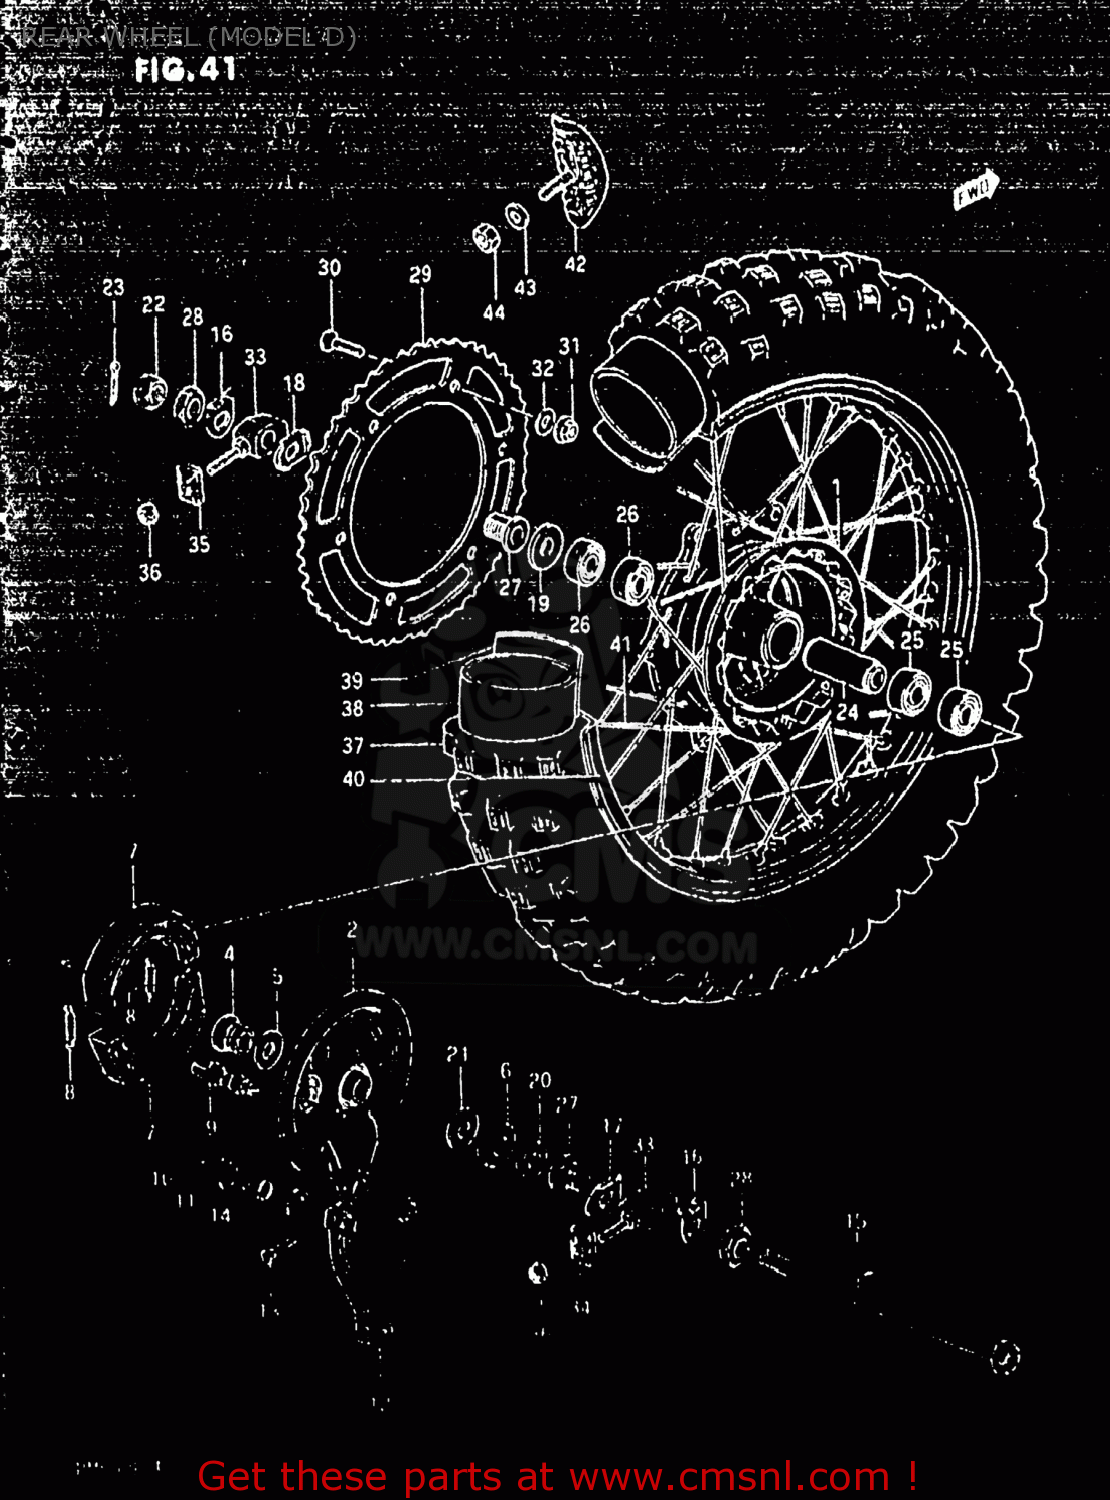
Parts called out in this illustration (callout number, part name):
1	DRUM,REAR HUB
2	PANEL SET,REAR HUB
3	SPHERICAL BRNG,TORQUE LINK
4	SPACER,RR BRAKE ANCHOR PANEL
5	SEAL,OIL(20X27X5)
6	CVR,RR BRAKE AHR PNL DUST SEAL
7	SHOE,BRAKE
8	SPRING
9	CAM,FR BRAKE
10	SPRING
11	O RING(D:2.5,ID:11.4)
12	LEVER,RR BRAKE CAM
13	BOLT
14	WASHER(12.5X20X1)
15	AXLE,REAR
16	WASHER,CHAIN ADJUSTER GUIDE
17	PLATE,CHAIN ADJUSTER,RIGHT
18	PLATE,CHAIN ADJUSTER,LEFT
19	SPACER,REAR AXLE,LEFT
20	SPACER,REAR AXLE,RIGHT
21	WASHER,THRUST
22	NUT
23	COTTER PIN
24	SPACER,REAR HUB BEARING
25	BEARING
26	BEARING
27	SPACER,CHAIN ADJUSTER
28	NUT
29	SPROCKET,REAR
30	SCREW(8X40)
31	NUT
32	WASHER
33	ADJUSTER,CHAIN
34	PLATE,CHAIN ADJUSTER GEAR
35	PLATE,CHAIN ADJUSTER GEAR
36	NUT
37	TIRE
38	TUBE,INNER
39	PROTECTOR,WHEEL,INNER
40	RIM,REAR WHEEL
41	SPOKE SET,REAR WHEEL
42	STOPPER,BEAD
43	WASHER
44	NUT
